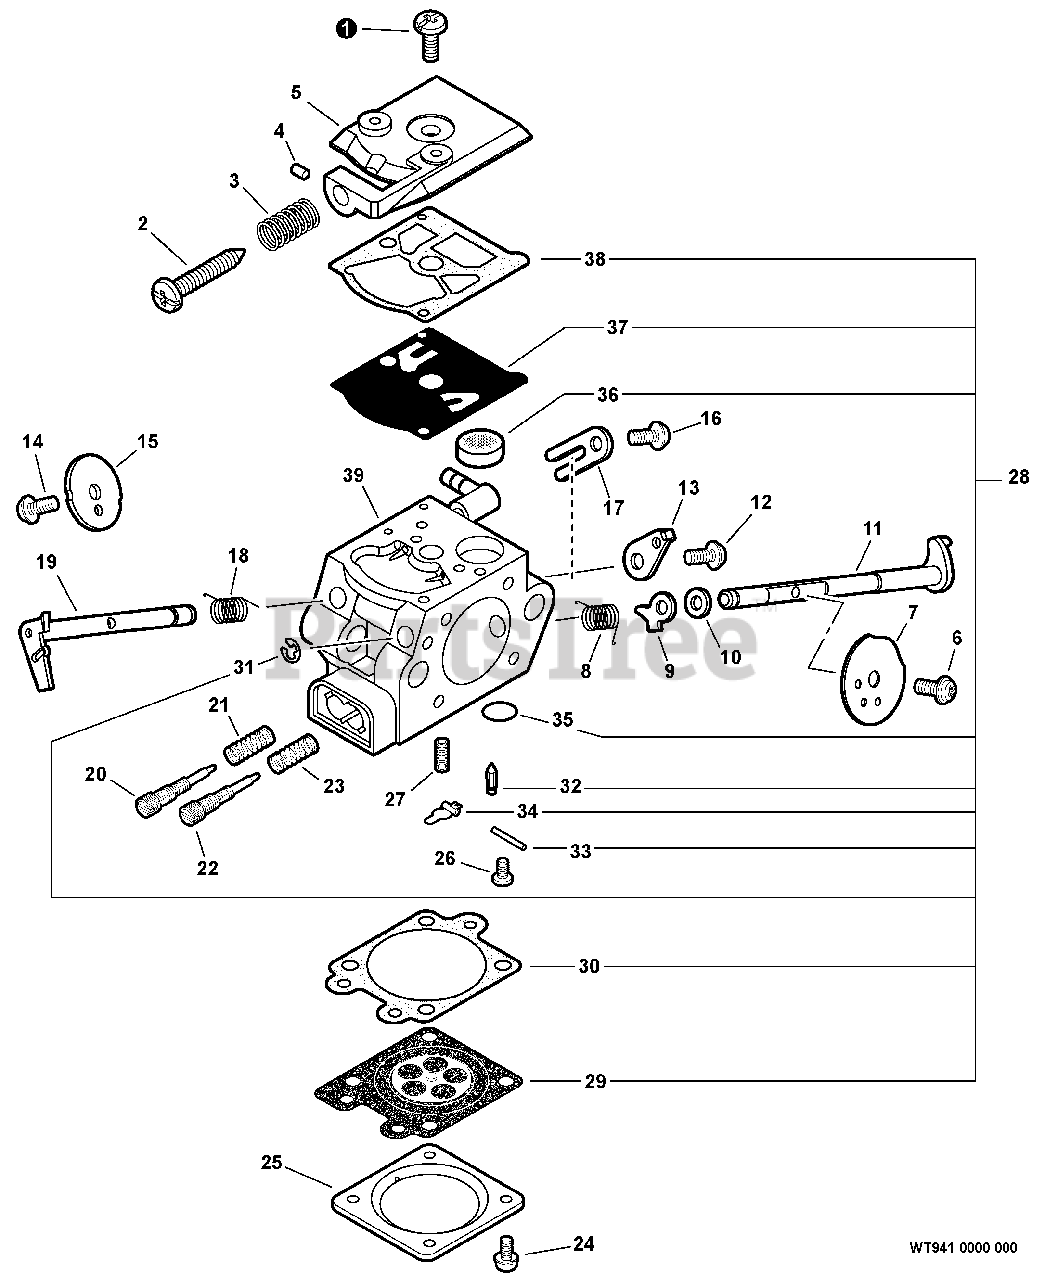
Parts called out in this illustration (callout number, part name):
1	SCREW, PUMP COVER
2	SCREW, IDLE ADJUST
3	SPRING, IDLE ADJUST
5	COVER, PUMP
7	VALVE, CHOKE
8	SPRING, CHOKE RETURN
9	LEVER, CHOKE
11	SHAFT, CHOKE
13	LEVER, THROTTLE
15	VALVE, THROTTLE
17	CLIP, THROTTLE SHAFT
18	SPRING, THROTTLE RETURN
19	SHAFT, THROTTLE
20	NEEDLE - HIGH SPEED
22	NEEDLE - LOW SPEED
25	COVER, METERING
26	SCREW, METERING LEVER PIN
27	SPRING, METERING LEVER
28	REPAIR KIT
29	DIAPHRAGM, METERING
30	GASKET, METERING
31	RING, RETAINING
32	VALVE, INLET NEEDLE
33	PIN, METERING LEVER
34	LEVER, METERING
35	PLUG, WELCH
36	STRAINER
37	DIAPHRAGM, PUMP
38	GASKET, PUMP
39	BODY, CARBURETOR
